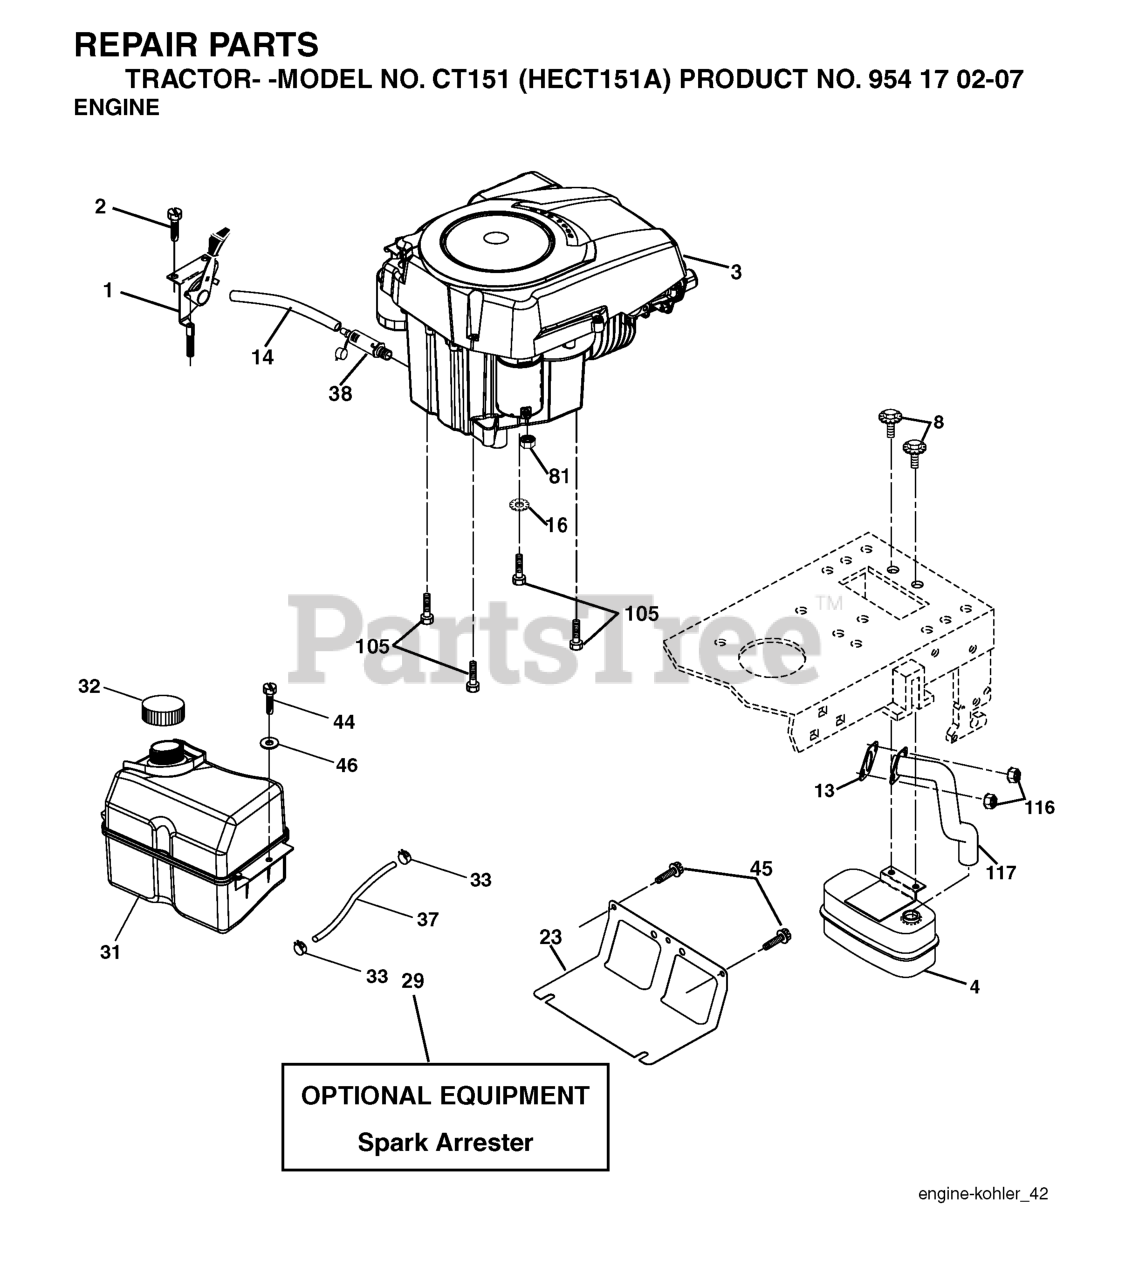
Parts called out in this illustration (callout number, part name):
1	CONTROL.THROTTLE.LT/YT
2	SCREW
4	MUFFLER.SINGLE.CYL.KOHL/B&S
8	BOLT.5/16-18UNCX3/4 W/SEMS.BLK
13	GASKET.EXHAUST.KOHLER
14	TUBE, DRAIN OIL ASM.
16	LOCKWASHER
23	SHIELD.BROWNING.DBR.GUARD
29	KIT.SPARK ARRESTOR 794945 B&S
31	FUEL TANK
32	FUEL CAP
33	HOSE CLAMP
37	LINE.FUEL.20
38	PLUG DRAIN OIL EASY
44	SCREW HEXWSHR 1/4-20X3/4
45	SCREW, 3/8-16X3/4
81	NUT
105	SCREW 3/8-16X1
116	NUT.HEX.FLANGE.TOPLOCK
117	RP.TUBE.EXHAUST.KOHL.COURAGE
